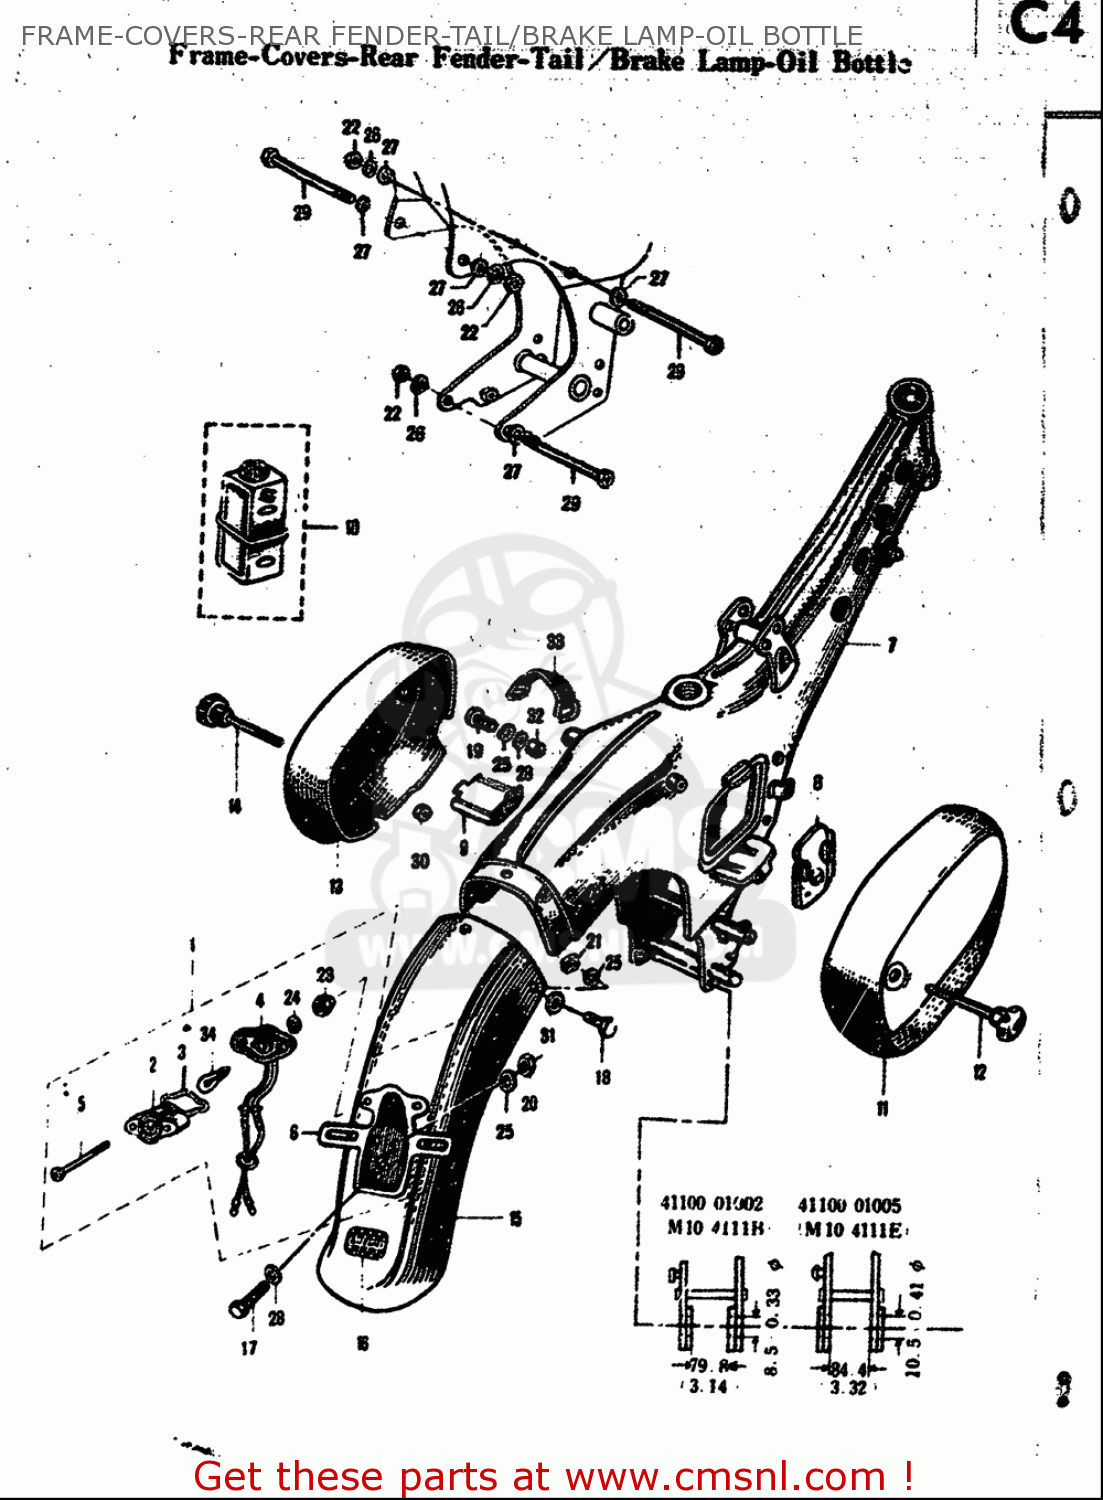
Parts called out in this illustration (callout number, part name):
18	BOLT
20	NUT
22	NUT
23	NUT
24	WASHER,LOCK
25	WASHER,LOCK
26	WASHER,LOCK
27	WASHER
28	WASHER
30	NUT
31	WASHER(6.5X18X1.6)
33	BAND
